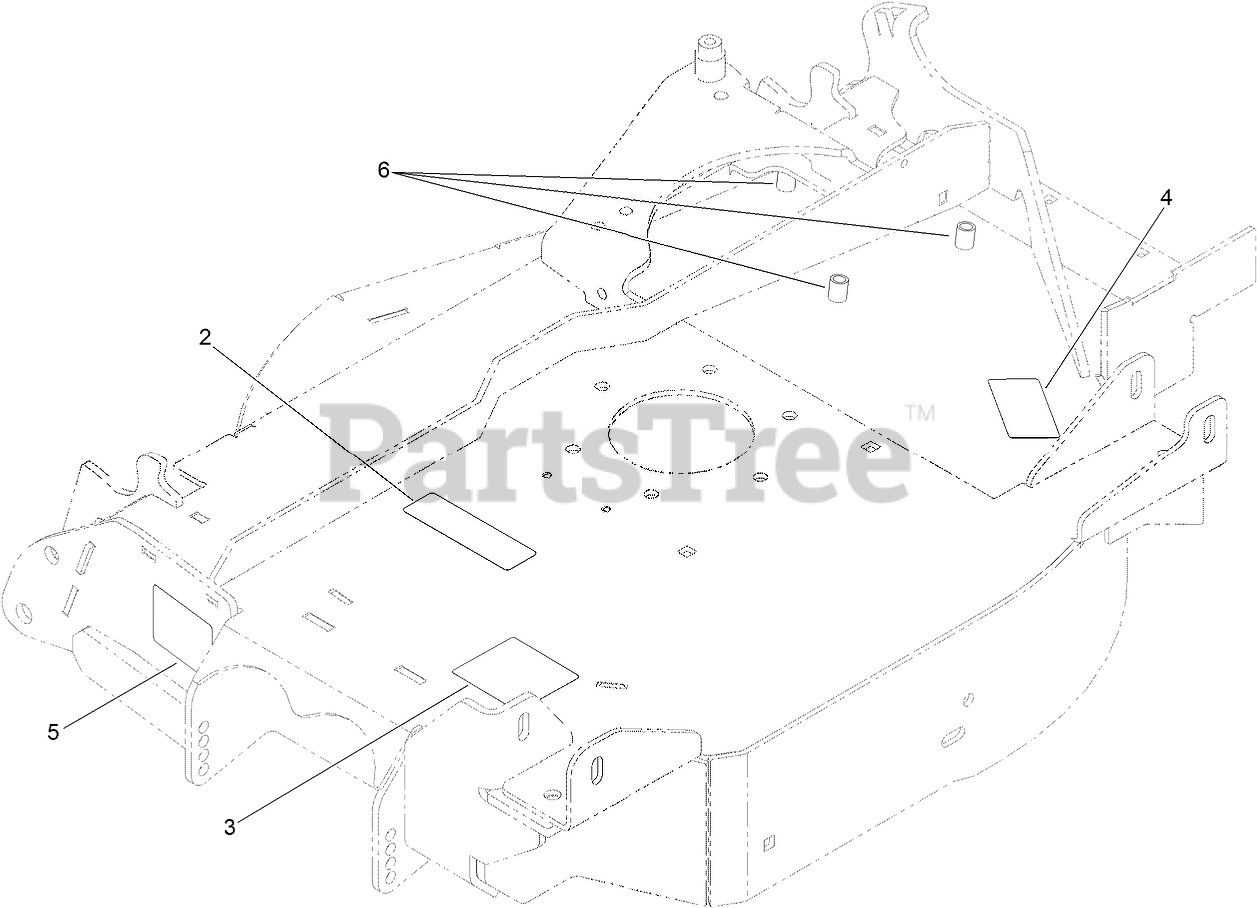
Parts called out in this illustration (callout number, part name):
2	DECAL-COVER, MISSING
3	DECAL-DANGER, THROWN OBJECT
4	DECAL-TORQUE, BOLT
5	DECAL-WARNING, PINCH POIN
6	NUT-CLINCH
